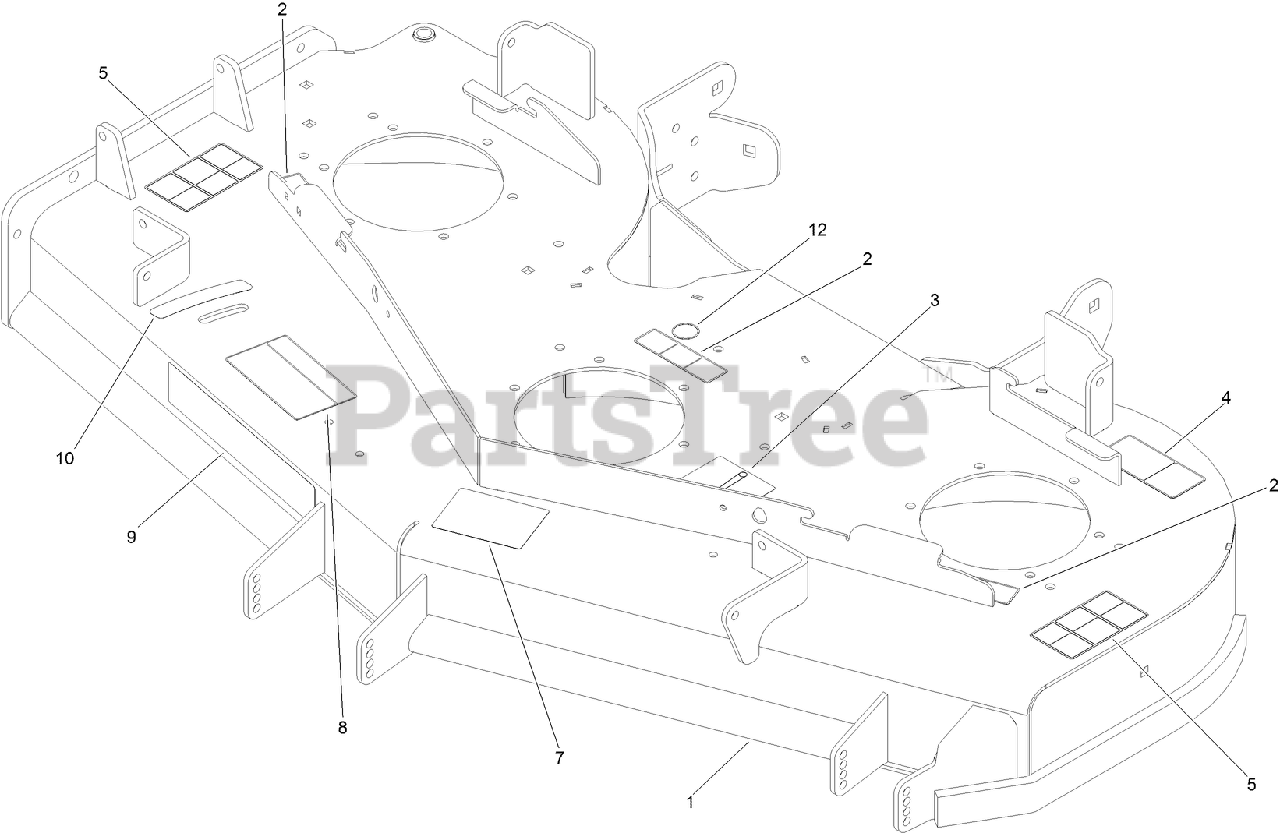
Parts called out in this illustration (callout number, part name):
1	DECK DECAL ASM
2	DECAL-COVER, MISSING
3	DECAL-ROUTING, DECK BELT
4	DECAL-TORQUE, BLADE BOLT
5	DECAL-DANGER
7	DECAL-SCALP, ANTI
8	DECAL-ADJUSTMENT, BAFFLE
10	DECAL-SETTING, BAFFLE
12	DECAL-GREASE
